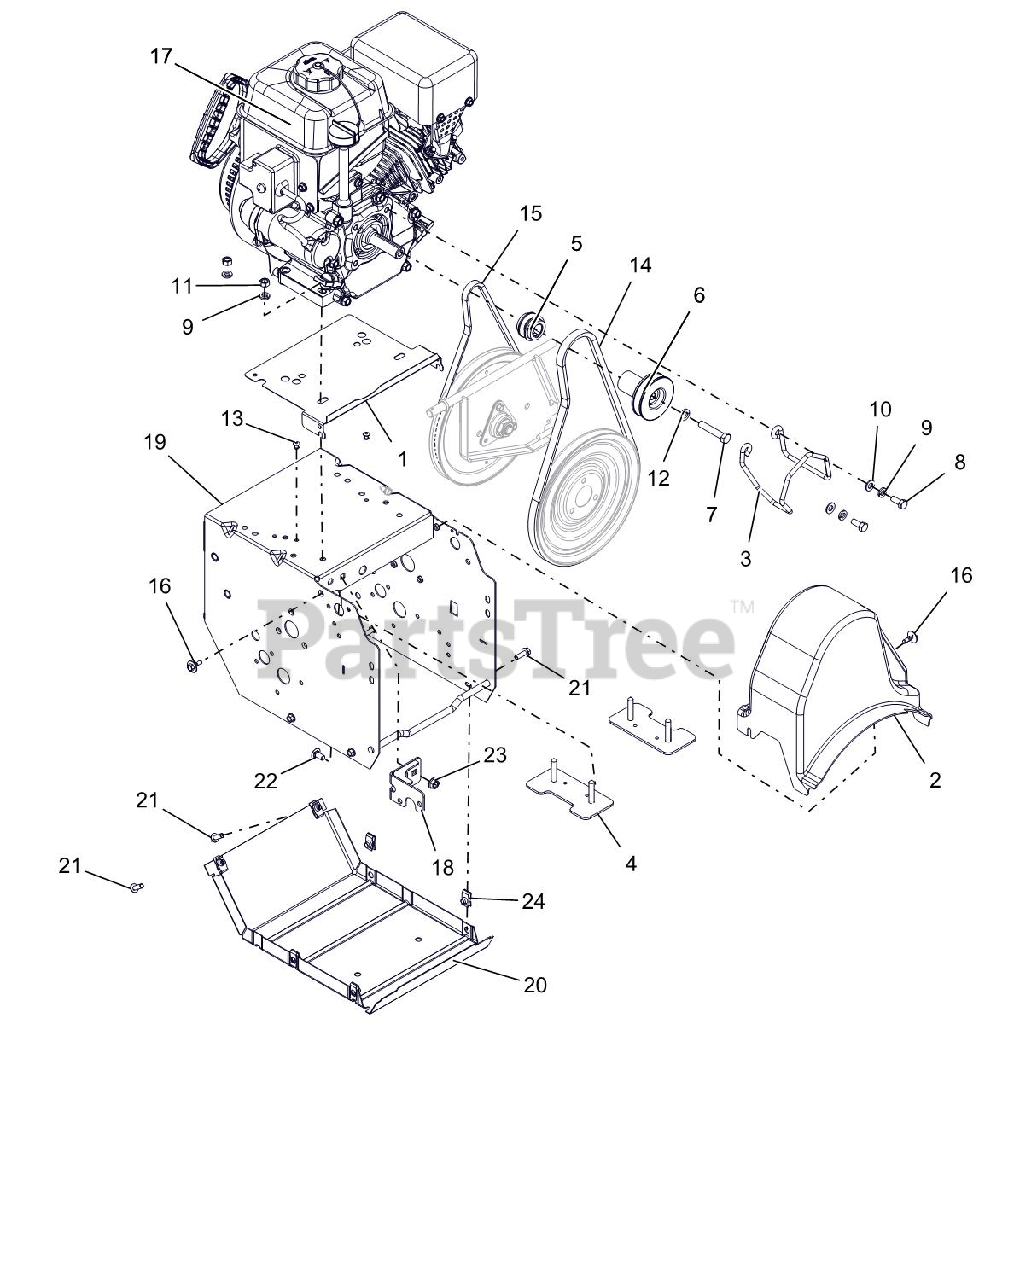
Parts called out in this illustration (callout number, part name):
1	BAFFLE, COMPACT
2	COVER, COMPACT BELT
3	FINGER, BELT
4	STRAP, ENGINE BOLT-WELDMENT
5	TRACTION SHEAVE HALF
6	SHEAVE, AUGER 3/4 - PM
7	BLT-HEX .38-24X2.0 YWZC
8	BLT-HEX .31-24X.75 YWZC GR5
9	WSHR-LK .312X.097 HVY YWZC
10	@WSHR-FL-STL.344X.688X.065YWZC
11	@NUT-HEX .31-18 YWZC
12	WSHR-LK .375X.115 HVY YWZC
13	RVT-POP .187 YZ
14	V-BELT, HA-RAW EDGE
15	V-BELT, 3L-WRAPPED
16	SCR-TAP .25-20X.5 CAPTIVE
18	WELDMENT, FRAME BRACKET
19	FRAME W/ENGINE BOLT STRAPS
20	COVER, BOTTOM
21	BLT-HEX .25-20X.75 HWH YZ GR5
22	@BLT-RHDSSQNK .31-18X.62 G5YZ
23	@NUT-LK-TOP-FLG .31-18 YWZC
24	NUT-RTNR .25-20X.56
